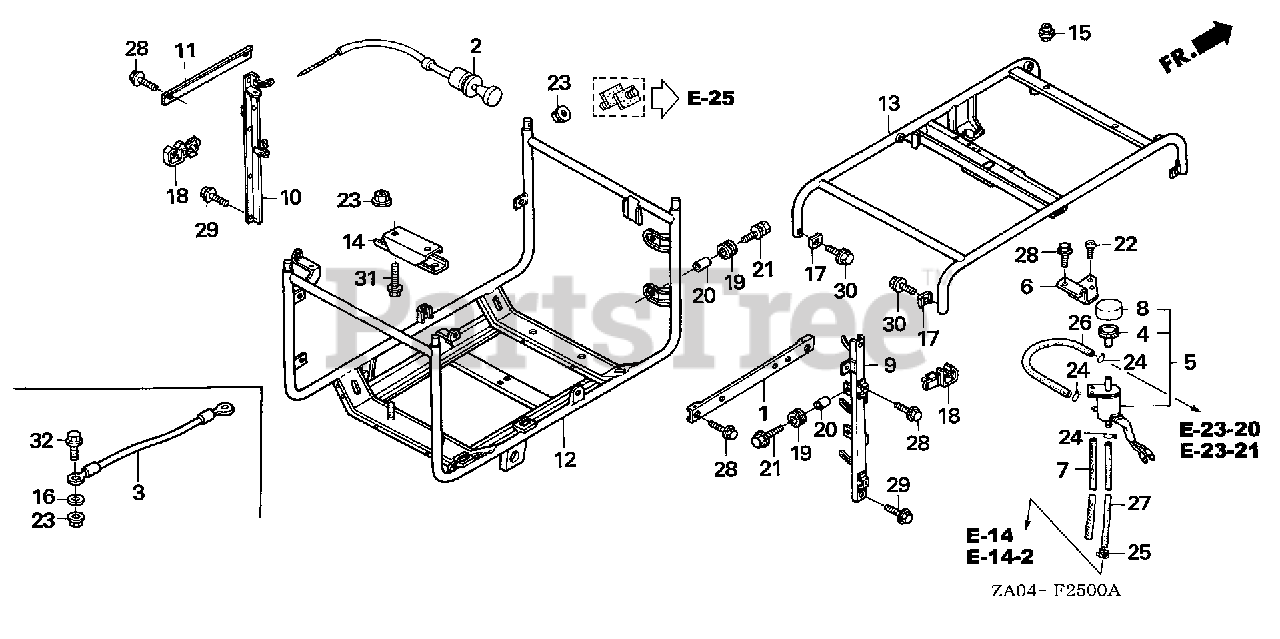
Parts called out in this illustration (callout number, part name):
1	STAY, FR. TANK
2	CABLE, CHOKE
3	CABLE, GROUND
4	FILTER ASSY., SOLENOID VALVE
5	VALVE ASSY., CONTROL
6	STAY, IDLE CONTROL
7	PROTECTOR, TUBE (9X210)
8	CAP, AIR FILTER
9	PILLAR, FR.
10	PILLAR, RR.
11	GUARD, RR.
12	FRAME (LOWER)
13	FRAME (UPPER)
14	RUBBER, GENERATOR MOUNTING
15	CUSHION, TOP COVER
16	WASHER, LOCK (10MM)
17	WASHER, FRAME JOINT
18	CLIP, HARNESS (5MM-15MM) (BLACK)
19	RUBBER, CONTROL BOX
20	COLLAR, CONTROL BOX
21	BOLT-WASHER (6X20)
22	SCREW, PAN (5X8)
23	NUT, FLANGE (10MM)
24	CLIP, TUBE (B7)
25	CLIP, TUBE (D8)
26	BULK HOSE, VACUUM (3.5X1000) (3.5X500) (BULK HOSE 95005-35008-10M)
27	BULK HOSE, VACUUM (3.5X1000) (3.5X500) (BULK HOSE 95005-35008-10M)
28	BOLT, FLANGE (6X12) Use up to Engine SN 1543277.
29	BOLT, FLANGE (8X12)
30	BOLT, FLANGE (8X16) Use up to Frame SN 1008045.
30	BOLT, FLANGE (8X16) Use from Engine SN 1000016.
31	BOLT, FLANGE (10X25)
32	BOLT, FLANGE (10X20)
